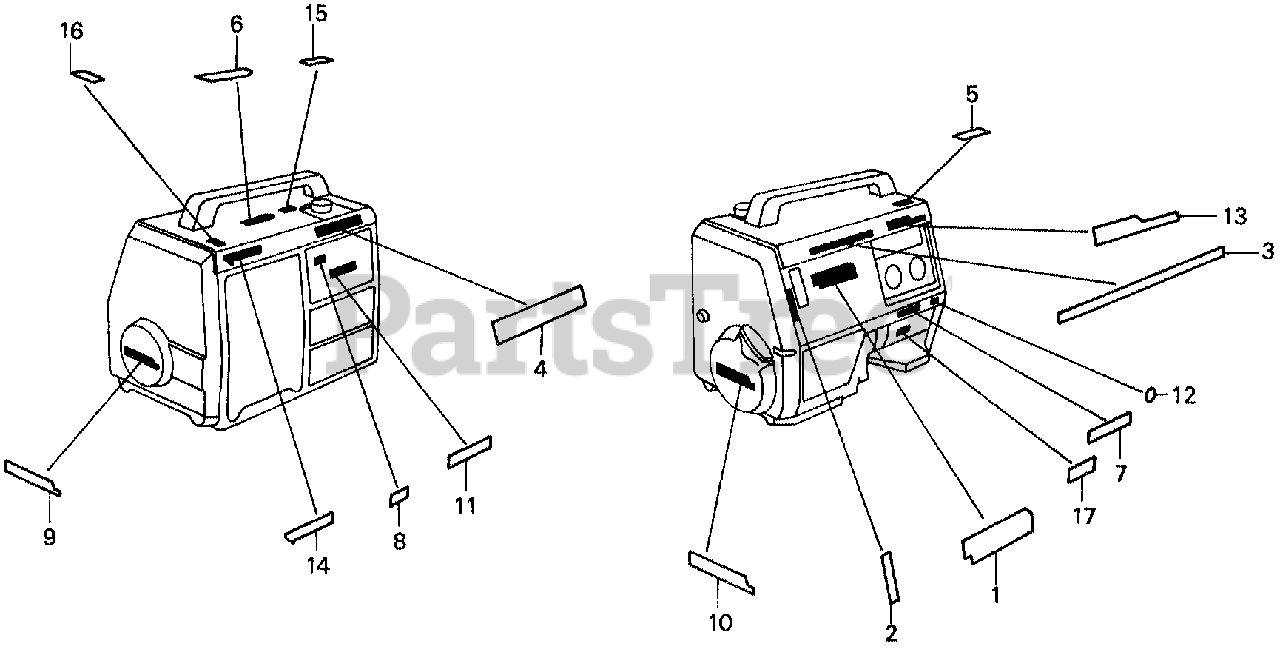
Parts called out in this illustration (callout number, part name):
1	EMBLEM
2	MARK, ENGINE SWITCH *TWHITE* (WHITE)
3	MARK, TOP RID *TWHITE* (WHITE)
4	PLATE A, CAUTION
5	LABEL, RAIN WARNING (ENGLISH)
6	MARK A, CAUTION
7	MARK, D.C. OUTPUT *TWHITE* (WHITE)
8	MARK, CHOKE
11	MARK, AIR CLEANER
12	MARK, GROUND
13	MARK, BREAKER
14	MARK, EX. CAUTION (ENGLISH/FRENCH)
15	LABEL, CONNECT WARNING (ENGLISH)
16	MARK, FUEL METER
17	MARK, OIL CAUTION
